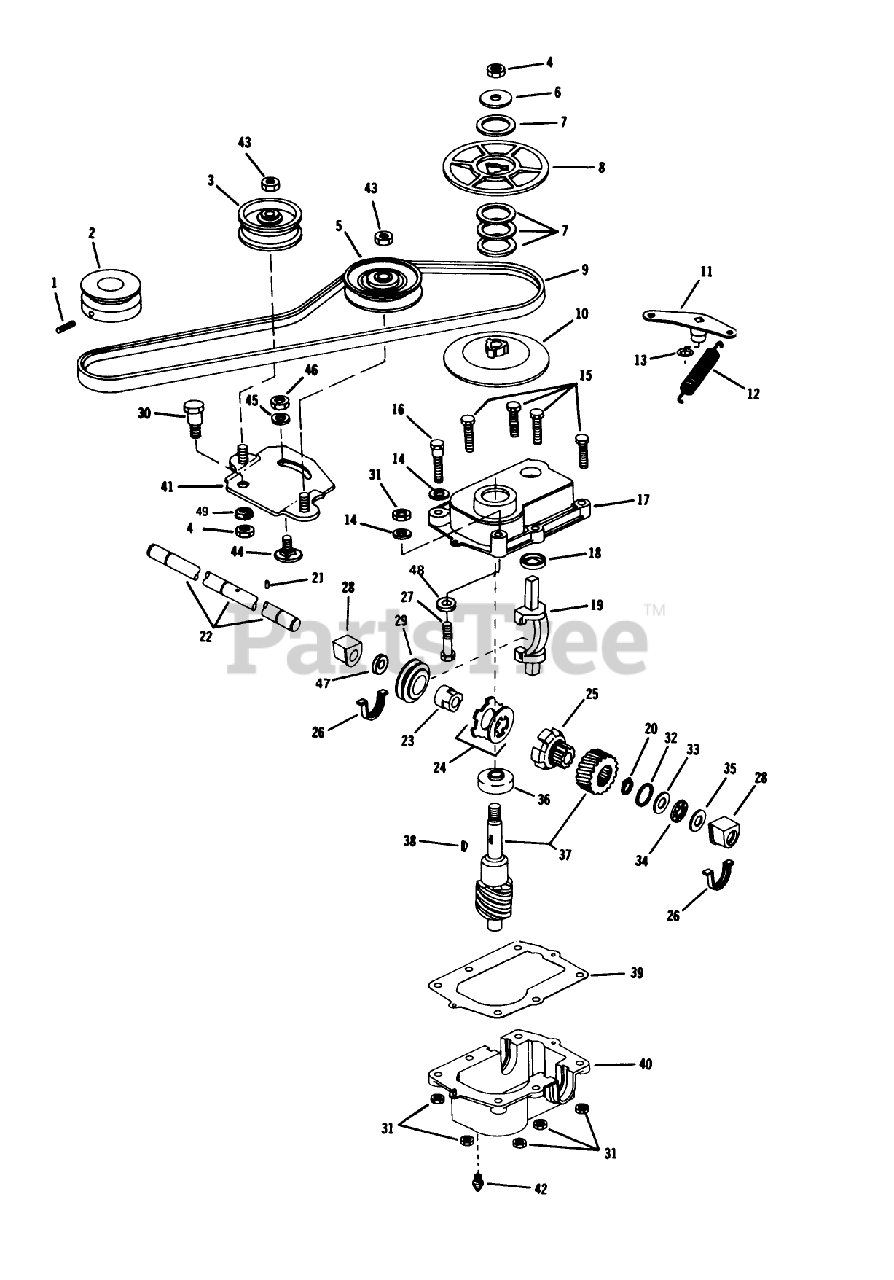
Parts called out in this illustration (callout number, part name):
1	SET SCREW F
2	PULLEY F
3	PULLEY NEWHAM IND *B
4	LOCKNUT
5	IDLER NEW HAM IND
6	WASHER
8	PULLEY UPPER PL
9	V-BELT
10	PULLEY LOWER PL
12	SPRING
13	O-RING
18	GUIDE ELCO
20	RET RING
21	PIN DRIVE LOCK
25	DRIVER BROCKWAY
28	BEARING & SEAL AY (12)
31	LOCKNUT E
33	WASHER-THRUST
35	THRUST WASHER
36	BEARING-BALL
38	KEY GALGER
39	GASKET HOOSIER
42	FITTING LINCOLN
43	NUT-JAM, LOCKING
46	NUT-LOCK F
47	WASHER
49	WASHER M
